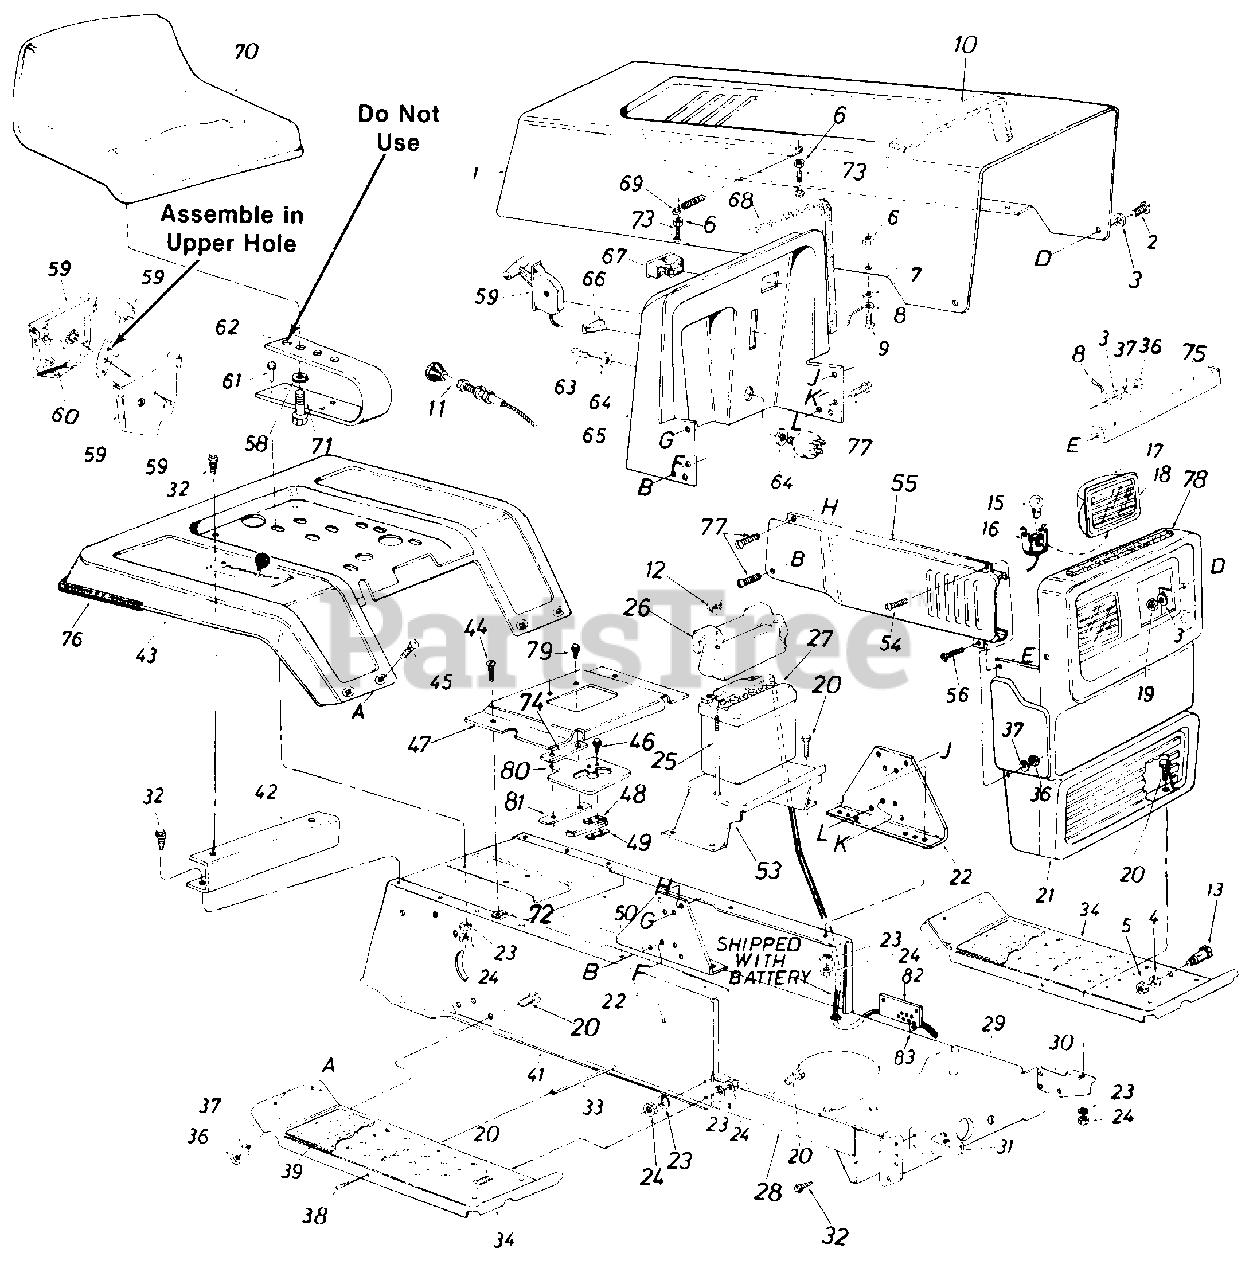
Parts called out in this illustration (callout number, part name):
1	Hood
2	Hex Scr. 1/4-20 x .62" Lg.
3	Fl-Wash. .296" I.D. x .62"O.D.
4	L-Wash. 3/8" I.D.
5	Hex Nut 3/8-16 Thd.
6	Hex Sems Nut #10-24 Thd.
7	Fl-Wash. .203" I.D. x .41" O.D. x .040
8	Hood Stop
9	Truss Hd. Scr. #10-24 x '/2" Lg.
10	PVC Foam
11	Choke Control
12	Wing Nut 1/4-20 Thd.-Plastic
13	Shld. Bolt .50" Dia. x .84
15	Lam p
16	Socket
17	Headlight Housing
18	Lens
19	Hex L-Nut 1/4-20 Thd.
20	Hex Bolt 5/16-18 x .75" Lg.
21	Grille
22	Dash Support Bracket
23	L-Wash. 5/16" I.D.
24	Hex Nut 5/16-18 Thd.
25	Battery Hold Down Rod
26	Battery Cover
27	12 Volt Battery
28	Lower Frame
29	Front Pivot Brk't.
30	Grille Mount Brk't.-L.H.
33	Running Board Rod
34	Running Board
36	Hex Nut 1/4-20 Thd.
37	L-Wash. 1/4" I.D.
38	Truss Mach. Scr. 5/16-18 x .75" Lg.
39	Foot Pad
41	R.H. Side Frame
42	Fender Mount Brace
43	Rear Fender
44	Truss Mach. Tap Scr. #10 x .50" Lg.
45	Carriage Bolt 1/4-20 x .50" Lg.*
46	Truss Hd. Scr. #10-24 x .50" Lg.*
47	Transmission Panel
48	Reverse Safety Switch
49	Insulator Nut Plate
50	Hitch Plate
53	Battery Bracket
54	Truss Hd. Scr. 1/4-20 x .75" Lg.*
55	Side Cover-R.H.
56	Truss Mach. Scr. 1/4-20 x .50" Lg.
58	L-Wash. 1/2" I.D.
59	Throttle Control Box Ass'y.
60	Throttle Control Wire
61	Hex Bolt 5/16-18 x 1.00" Lg.*
62	Seat Spring 5.5" High
63	Ignition Key
64	Ignition Switch
65	Dash Panel
66	Light Switch
67	Ammeter
68	Trim Strip-27"
69	Hood Spring
70	Seat Ass'y.
71	Hex Bolt 1/2-13 x 1.0" Lg.
72	Speed Nut #10Z
73	Hex Scr. #10-24 x 1.0" Lg.
74	Spacer Plate
75	Tie Strap-Grille/Side Panel
76	Trim Strip-81"
77	Hex Wash. Hd. Tap Scr. 1/4 x.75" Lg.
78	Foam Strip 3/8 x 1 x 14" Lg.
79	Truss Mach. Scr. 1/4-20 x .75" Lg.
80	Gear Selection Plate
81	Clamping Plate
82	Brake Cable Bracket
83	Cable Tie
